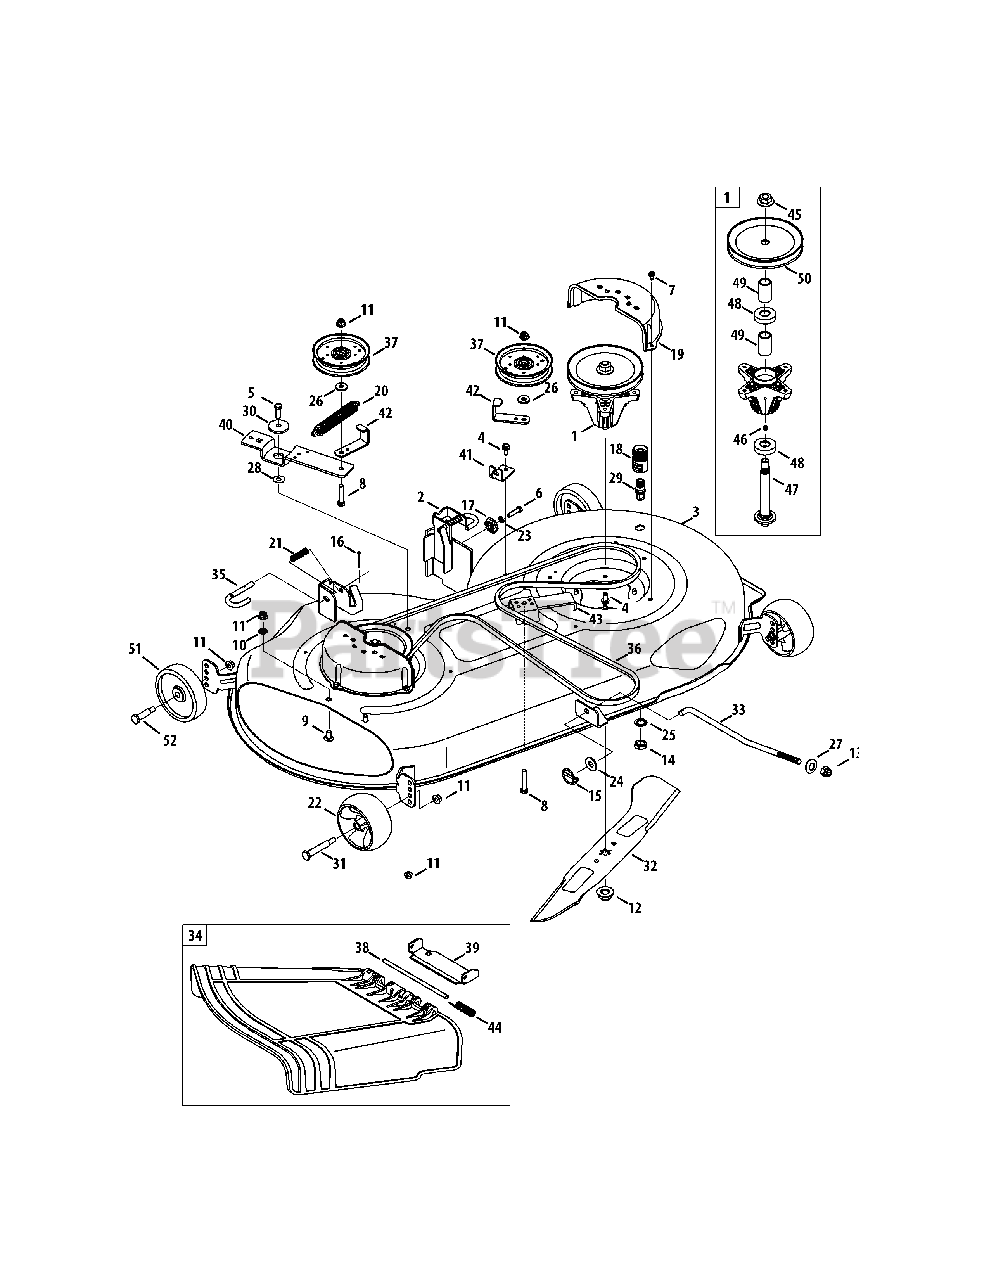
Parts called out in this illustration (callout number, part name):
1	Spindle Assembly, Pulley 6.93 Dia.
3	Deck Assembly, Offset, 46"
4	Screw, Self-tapping, 5/16-18, .750,
5	Hex Screw, 3/8-16, 1.00, Gr5, Std
6	Hex Screw, 5/16-18, 1.25, Gr5, Std
7	Screw, Self-tapping, 1/4-20, 0.500,
8	Hex Screw, 3/8-16, 2.00, Gr5, Std
9	Bolt, Carriage, 3/8-16, 0.75, Gr1
10	Nut, Push, 3/8
11	Nut, Flange Lock, 3/8-16, Nylon
12	Nut, Flange, 5/8-18
13	Nut, 1/2-13
14	Nut, Hex, M16-1.5 Din 936
15	Pin, Lynch, .1875
16	Pin, Cotter, 1/8 X 1.25
17	Gear, Deck, Adj
18	Adapter, Water
19	Cover, Belt, Universal
20	Spring, Extension, .94 Dia. X 6.74
21	Spring, Compression, .535 OD X 1.75
22	Wheel, Deck, 5.0 Dia. Ball
23	Washer, Lock, 5/16, Regular Duty
24	Washer, Flat, .531 X 1.25 X .100
25	Washer, Lock, 5/8, Int. Tooth
26	Washer, Flat, .385 X .870 X .092
27	Washer, Bell, .63 X 1.25 X .18
28	Washer, Flat, .385 X 1.0 X .030
29	Port, Water
30	Spacer, Shoulder, .8840 X .190
31	Bolt, Shoulder, .496 X 2.50, 3/8-16
32	Blade, Cut, 23.25" 2-In-1
33	Rod, Lift, Deck, Front, 13.7
34	Chute Assembly, 46" Deck
35	Rod, Deck Release .375 Dia.
36	Belt, V-Type, A Sec
37	Pulley, Idler, 4.25" Dia.
38	Pin, Hinge, 7.96
39	Bracket, Chute
40	Bracket, Idler, Pivot
41	Bracket, Cable, Deck Engage
42	Bracket, Guard, Belt, 4.25 Pulley
43	Bracket, Support, Stationary Idler
44	Spring, Torsion, .44 I.D. X 2.0
45	Nut, Flange, 5/8-18
46	Lube Fitting, 3/16
47	Shaft, Spindle, 6.11
48	Bearing, Ball, .787 X 1.85 x.551
49	Spacer, .792 X 1.060 X 1.860
50	Pulley, Deck, 6.93 Dia.
51	Wheel, Deck 5.0 x 1.38
52	Bolt, Shoulder, .496 x 1.525, 3/8-16
